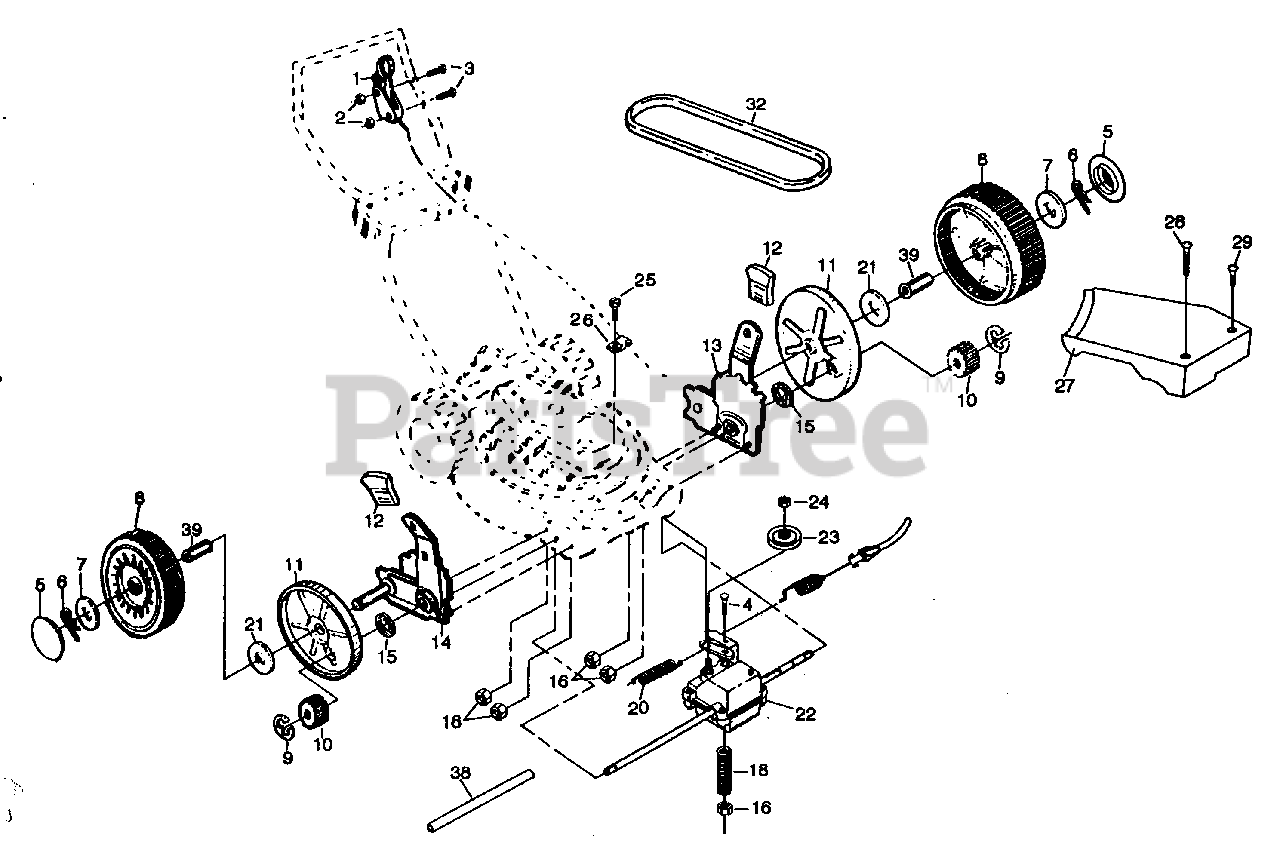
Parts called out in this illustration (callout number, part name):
1	Drive Control (AYP part number)
2	Locknut #10-24 (AYP part number)
3	Pan Head Machine Screw #10-24 x 2 (AYP part number)
4	Carriage Bolt 1/4-20 x 2 (AYP part number)
5	Hubcap (AYP part number)
6	Retainer Clip (AYP part number)
7	Washer (AYP part number)
8	Wheel & Tire Assembly (AYP part number)
9	E-ring (AYP part number)
11	Dust Cover
12	Selector Knob
13	Wheel Adjuster Assembly (Left) (AYP part number)
14	Wheel Adjuster Assembly (Right) (AYP part number)
15	Felt Washer (AYP part number)
16	Locknut (AYP part number)
18	Spring (AYP part number)
21	Washer 1/2 x 1-1/2 x .134 (AYP part number)
22	Gear Case Assembly (AYP part number)
23	Drive Pulley (AYP part number)
24	Locknut (AYP part number)
25	Hex Head Screw # 10-2 (AYP part number)
26	Guide Clip (AYP part number)
27	Drive Cover
28	Pan Head Tapping Screw #10-24 x 2-3/4 (AYP part number)
29	Pan Head Tapping Screw #10-24 x 1-3/4 (AYP part number)
32	V-Belt
38	Drive Shaft Cover (AYP part number)
39	Wheel Bushing (AYP part number)
